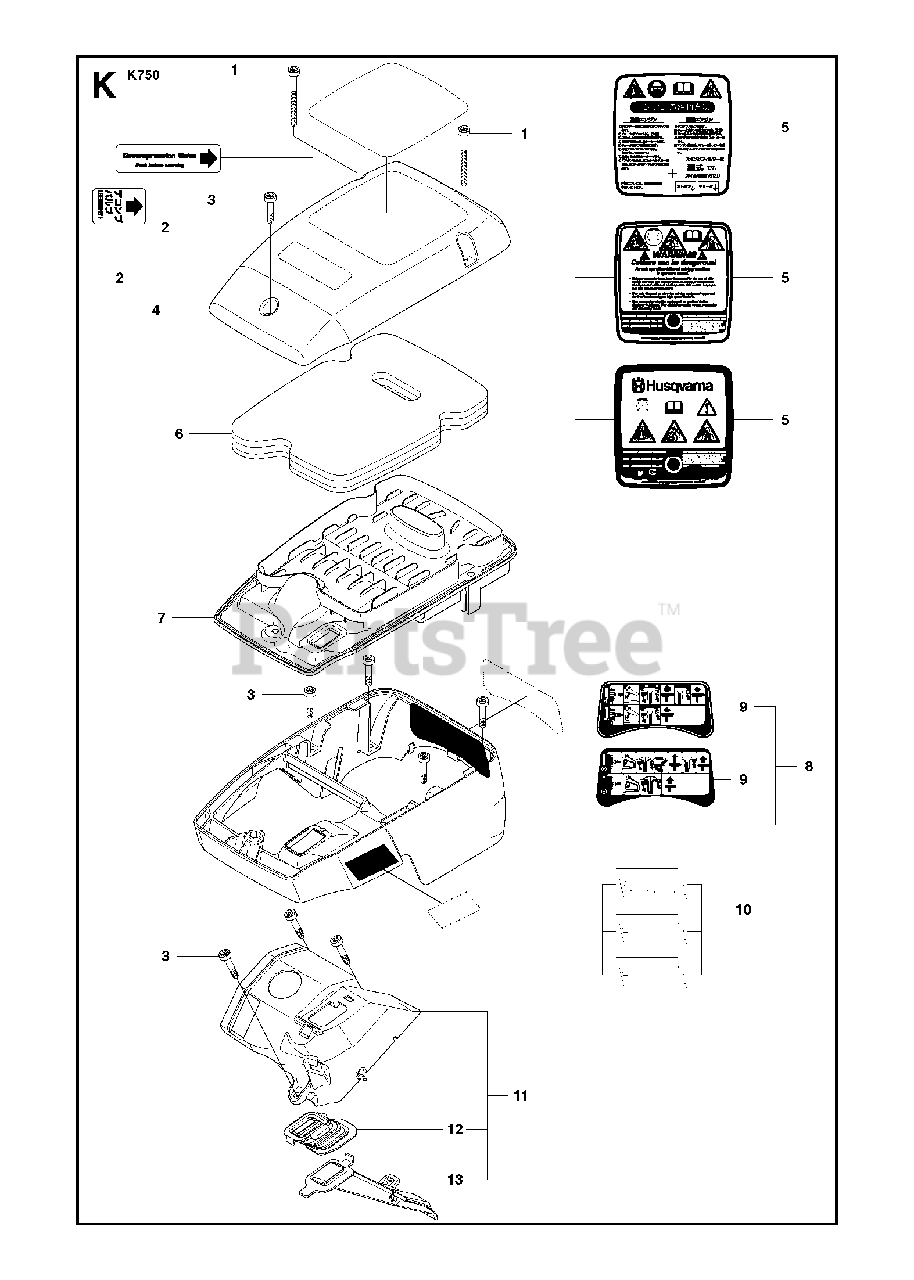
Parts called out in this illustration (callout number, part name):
1	SCREW ITXSCM
3	SCREW ITXSCM
4	FILTER COVER
5	LABELEPA USA
5	LABELEPA Canada
7	FILTER BOTTOM
8	CYLINDER COVER ASSYIncl. 9
8	CYLINDER COVER ASSYIncl. 9, Purge
11	COVERIncl. 12, 13
12	BELLOWS
